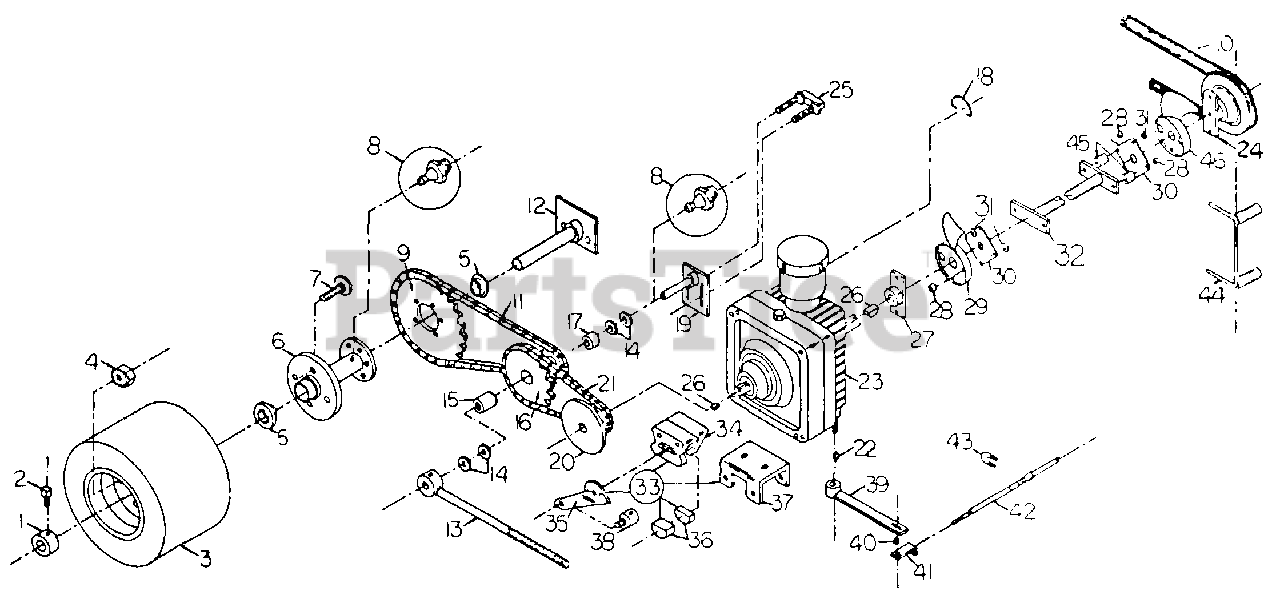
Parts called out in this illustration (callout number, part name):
1	Set Collar, 1"
2	Squarehead Setscrew, 5/16-18 x 1/2"
3	Drive Wheel Ass'y., 16 x 7.50-8
4	Lug Nut, 1/2-20
5	Drive Wheel Bearing
6	Drive Wheel Hub
7	Lug Bolt, 1/2-20 x 1 1/4"
8	Self-tapping Zerk, 1/4-28
9	Final Drive Sprocket, 40A 54
10	Transmission Belt
11	Final Drive Chain
12	Drive Wheel Axle
13	Support Collar
14	Machine Washer, 3/4", 10 GA
15	Idler Sprocket Bearing, 1/2"
16	Idler Sprocket
17	Idler Sprocket Bearing, 3/4"
18	Transmission Dump Valve Clip
19	Idler Sprocket Shaft
20	Transmission Sprocket w/Brake Disc
21	Primary Drive Chain
22	Woodruff Key, 1/8" x 3/8"
23	Transmission, LH
24	Pulley w/Drive Plate
26	Woodruff Key, 1/8" x 1/2"
27	Hub w/Drive Plate
30	Drive Plate
31	Washer, 1/4", 10 GA
33	Brake Assembly, LH
34	Brake Caliper
35	Caliper Lever, LH
36	Brake Pad (Set)
37	Caliper Bracket
38	Caliper Rod Collar
39	Transmission Arm, LH
40	Cable End Bushing
41	Steering Cable End
42	Steering Cable
43	Steering Cable Clamp
44	Transmission Belt Retainer
